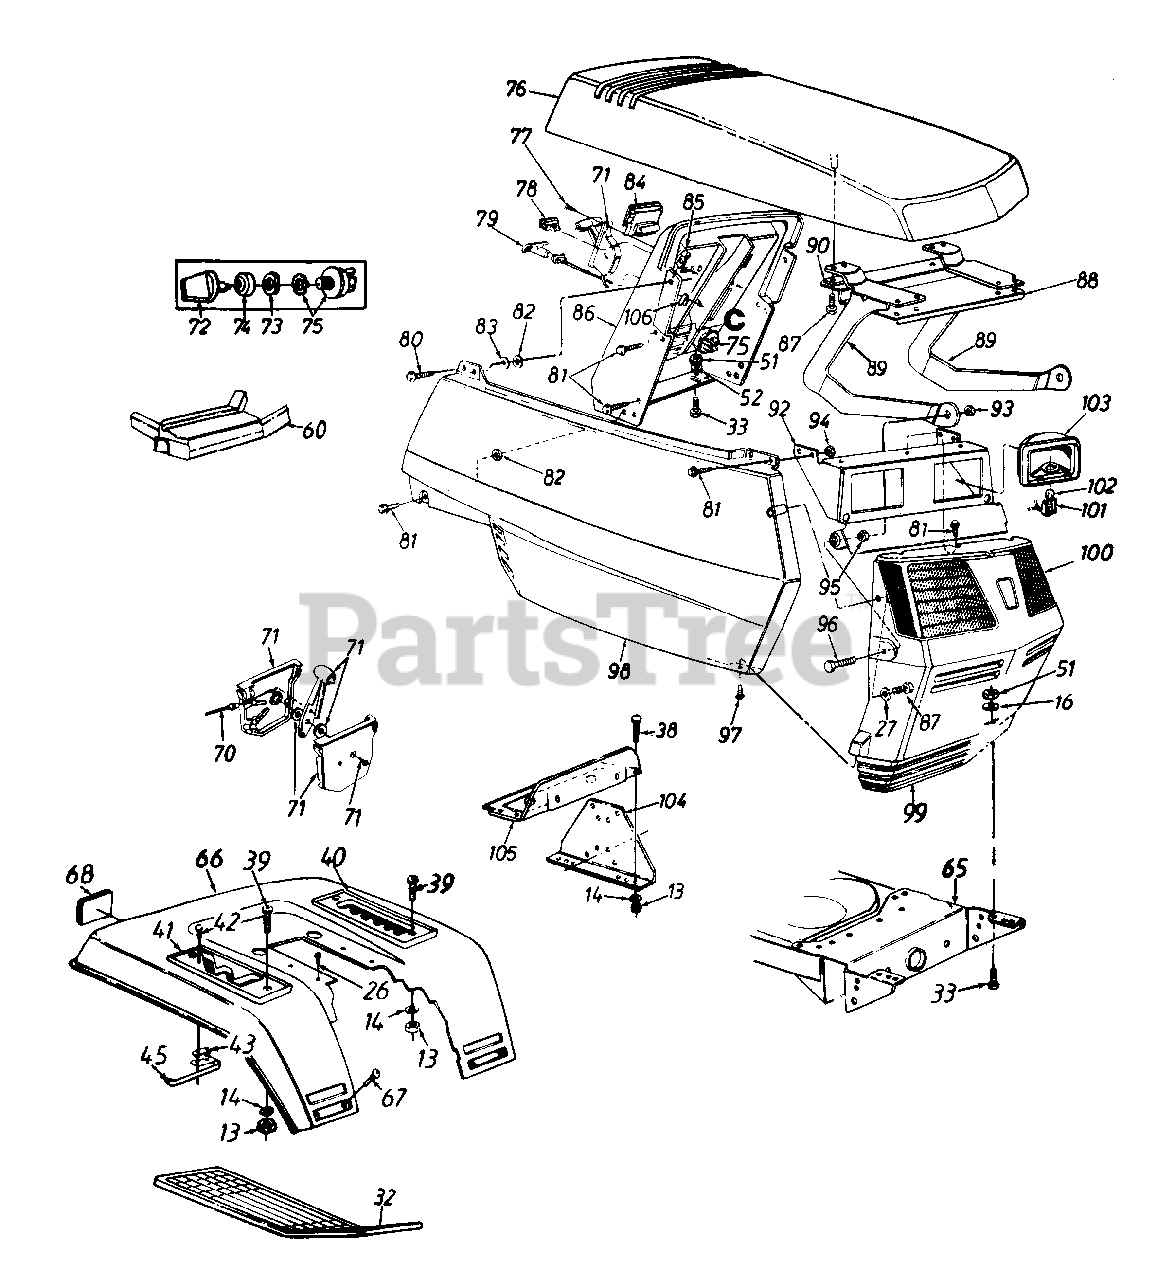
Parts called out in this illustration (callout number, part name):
13	Hex Nut 1/4-20 Thd.
14	L-Wash. 1/4" I.D.
16	Fl-Wash. .344" I.D. x 1" O.D.
26	Hex Wash. Hd. AB-Tap Scr. 5/16 x .75" Lg.
27	Fl-Wash. .218" I.D. x .5" O.D.
32	Rubber Foot Pad - L.H.
33	Hex Bolt 5/16-18 x .75" Lg.
38	Hex Bolt 1/4-20 x .62" Lg.
39	Truss Mach. Scr. 1/4-20 x .75" Lg.
40	7-Speed Index Brkt.
41	Forward/Reverse Index Brkt.
42	Hex Wash. Hd. AB-Tap Scr. #8 x .5" Lg.
43	Insulator Nut Plate
45	Reverse Safety Switch
51	Hex Nut 5/16-18 Thd.
52	Fl-Wash. .343" I.D. x .687"
60	Steering Wheel Insert
68	Reflector
70	Throttle Wire 18.5" Lg.
71	Throttle Control Box Ass'y.
72	Ignition Key
73	Ignition Switch Nut
74	Ignition Switch Cap
75	Ignition Switch
76	Hood (Yellow)
77	Truss Mach. AB-Tap Scr. #10 x .5" Lg.
78	Light Switch
79	Choke Control
80	Hex Wash. Hd. Tap Scr. 1/4 x .75" Lg.
81	Hex Tap Scr. 1/4-20 x .5" Lg.
82	Push Nut Fastener
83	Fl-Wash. .27" I.D. x .948"
84	Ammeter
85	Speed Nut 1/4-20 Thd.
86	Dash Panel
87	Hex Wash. Hd. B-Tap Scr. 1/4 x .62" Lg.
94	Hex L-Nut 1/4-20 Thd.
95	Hex Jam Nut 5/16-18 Thd.
96	Hex Bolt 5/16-18 x 7/8" Lg.
97	Truss Mach. B-Tap Scr. #10 x .5" Lg.
98	Side Cover - R. H. (Yellow)
99	Grille (Yellow)
100	Lens - L.H.
101	Twist Lock - Lamp Socket
102	Lamp
103	Headlight Housing
